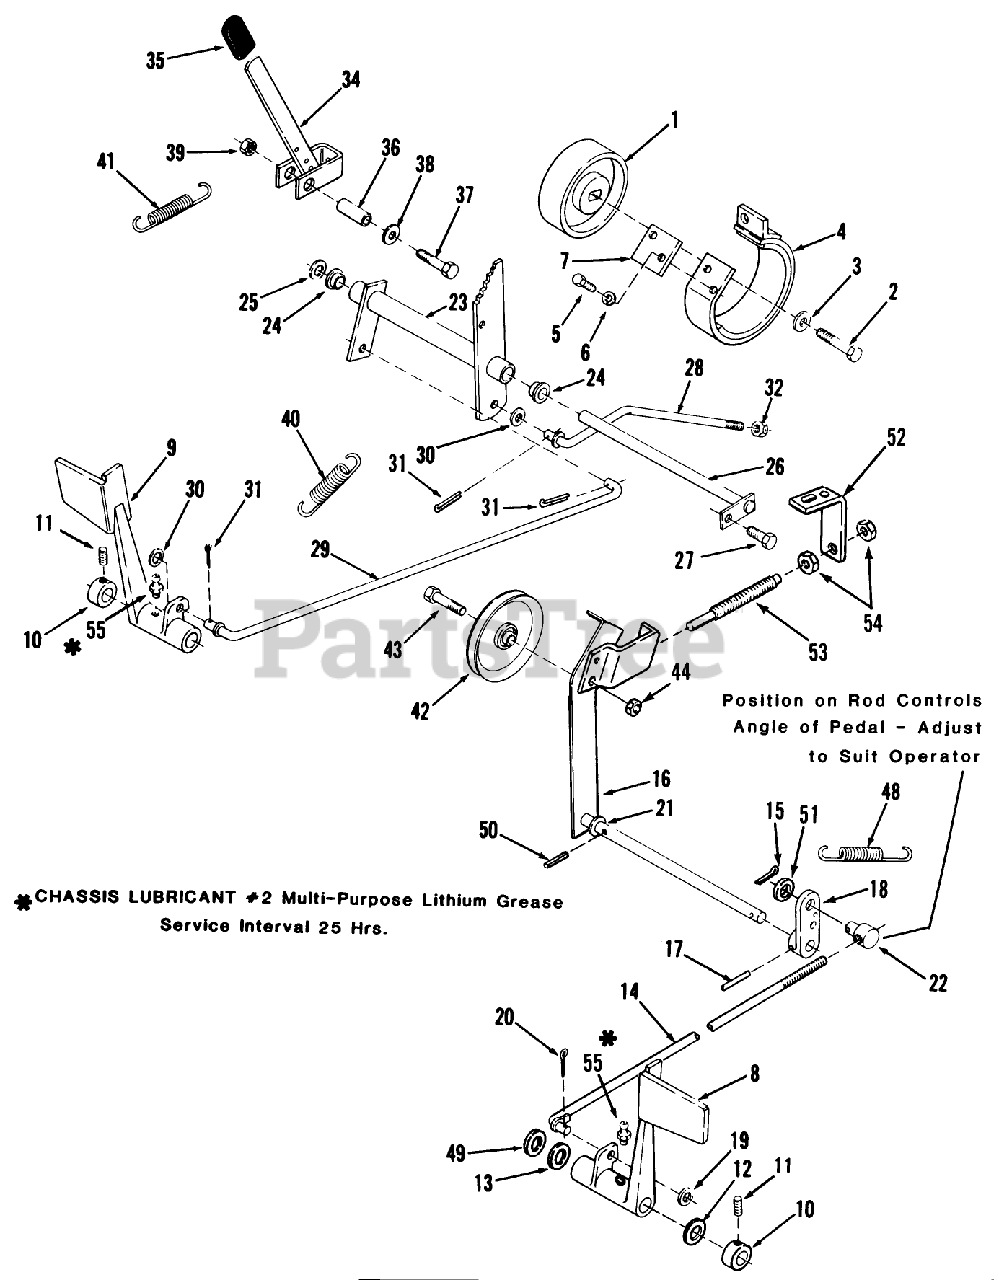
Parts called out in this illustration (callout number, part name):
1	DRUM-BRAKE
2	SCREW-HEX HD CAP
3	WASHER
4	BRAKE BAND ASM
12	WASHER-BOWED
13	WASHER
14	ROD AND GUIDE ASM
17	PIN-SPIROL
19	WASHER-NYLON
21	SHIM-WASHER
22	TRUNNION
24	BUSHING-FLANGED
26	ROD ASM
27	SCREW
28	ROD-REAR BRAKE
30	WASHER-NYLON
31	Hairpin
35	GRIP
36	SPACER
40	SPRING-BRAKE
41	SPRING-EXTENSION
43	BOLT-SPECIAL HEX
48	SPRING-CLUTCH
50	PIN-SPIROL
52	BRKT-DAMPER *B
